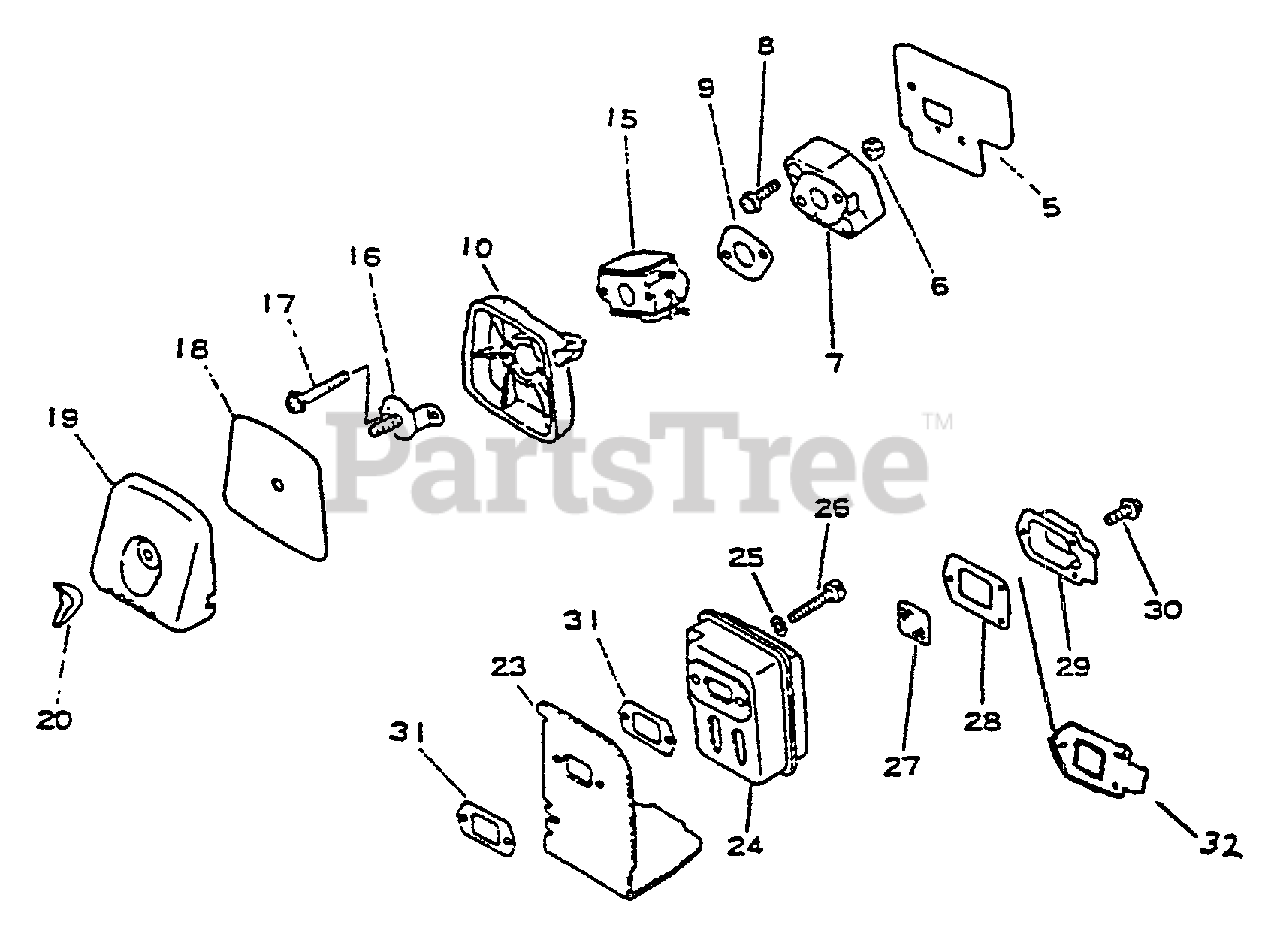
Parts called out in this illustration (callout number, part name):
5	GASKET, INTAKE
7	INSULATOR, INTAKE
8	SCREW - 5X22
9	GASKET, INTAKE
10	AIR FILTER CASE ASSY
15	CARBURETOR
16	PLATE, PREVENT
17	SCREW - 5X64
18	FILTER, AIR
19	COVER, AIR FILTER - BLACK
20	WINGNUT - 5
23	SHIELD, EXHAUST
24	MUFFLER
25	WASHER - 5
26	SCREW - 5X55
27	SCREEN, SPARK ARRESTOR
28	GASKET, EXHAUST
29	GUIDE, EXHAUST - INNER
30	SCREW - 4X10
31	GASKET, EXHAUST
32	GASKET, EXHAUST - INNER
